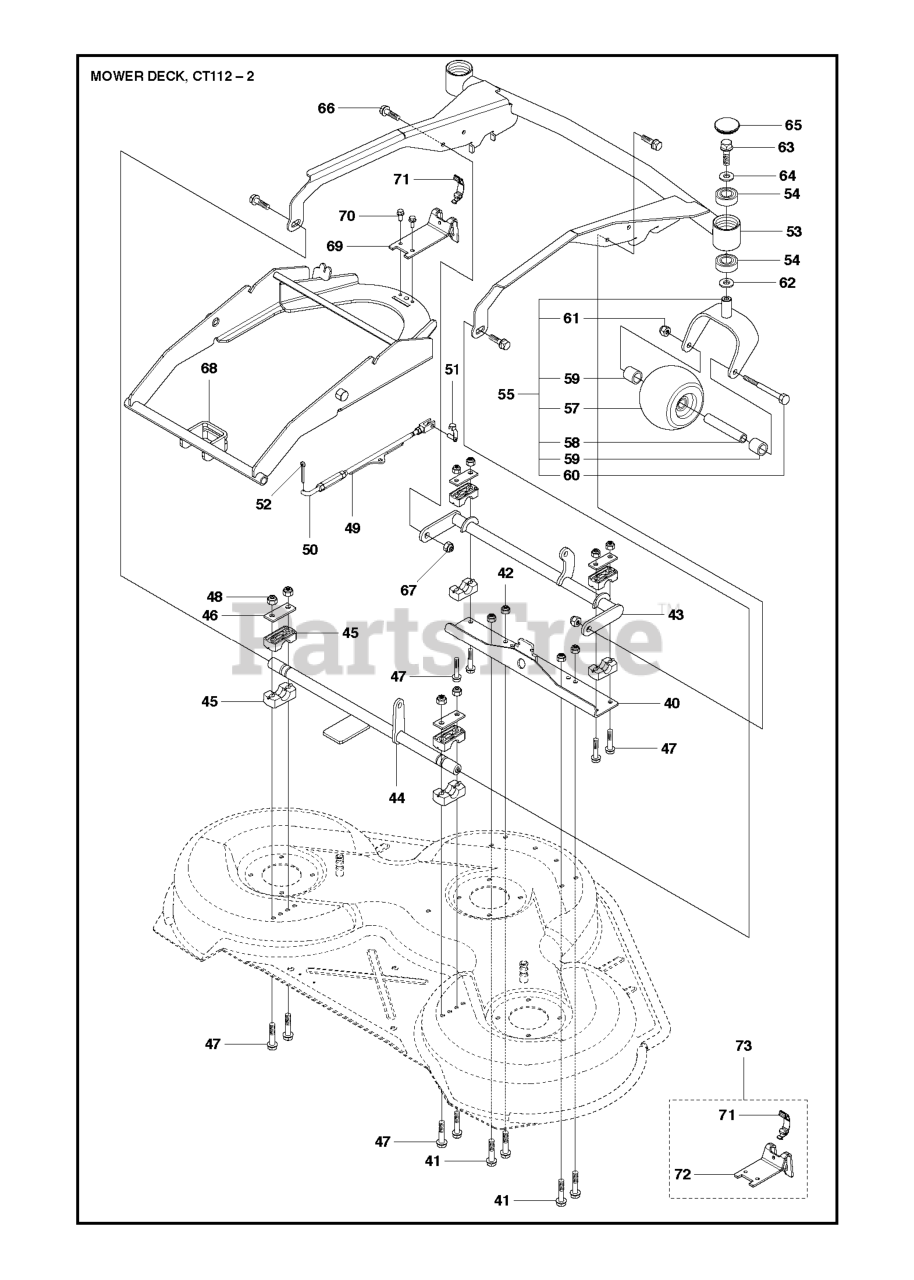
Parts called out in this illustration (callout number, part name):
42	LOCKNUT M8
48	LOCKNUT M8
50	PARALLEL ROD
54	BALL BEARING 6004-2RS1
55	PIVOT WHEELS
57	DECK ROLLER, FRONT
61	NUT
65	HUB CAP PIVOT WHEEL
67	LOCKNUT M8
70	SCREW
71	CLIP GRAY
